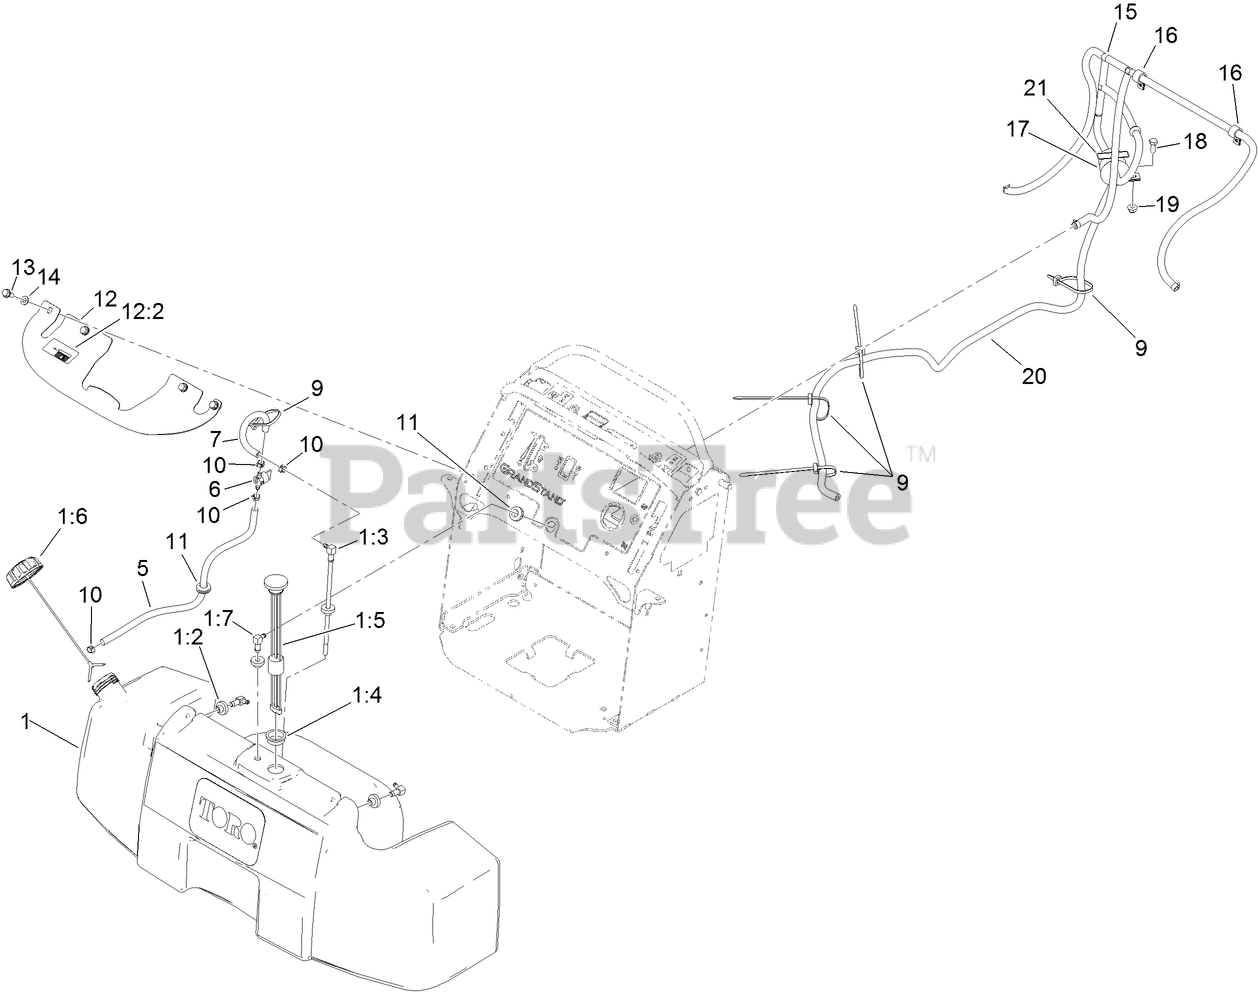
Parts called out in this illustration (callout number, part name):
1	TANK ASM
1:2	BUSHING
1:3	FITTING-FUEL, SCREEN TUBE
1:4	GROMMET
1:5	GUAGE-FUEL
1:6	CAP-FUEL, RATCHETING
1:7	ELBOW-90 DEG
5	HOSE-FUEL
6	VALVE-FUEL
7	HOSE-FUEL
9	TIE-CABLE
10	CLAMP-HOSE
11	GROMMET
12	BRACKET-TANK
12:2	DECAL-FILL, FUEL
13	SCREW-HWHTF
14	WASHER-FLAT
15	VENT HOSE ASM
16	CLAMP-CABLE
17	CLAMP-R
18	SCREW-HH
19	NUT-HF, NI
20	HOSE-FUEL
21	DECAL-FILTER, EMISSIONS
